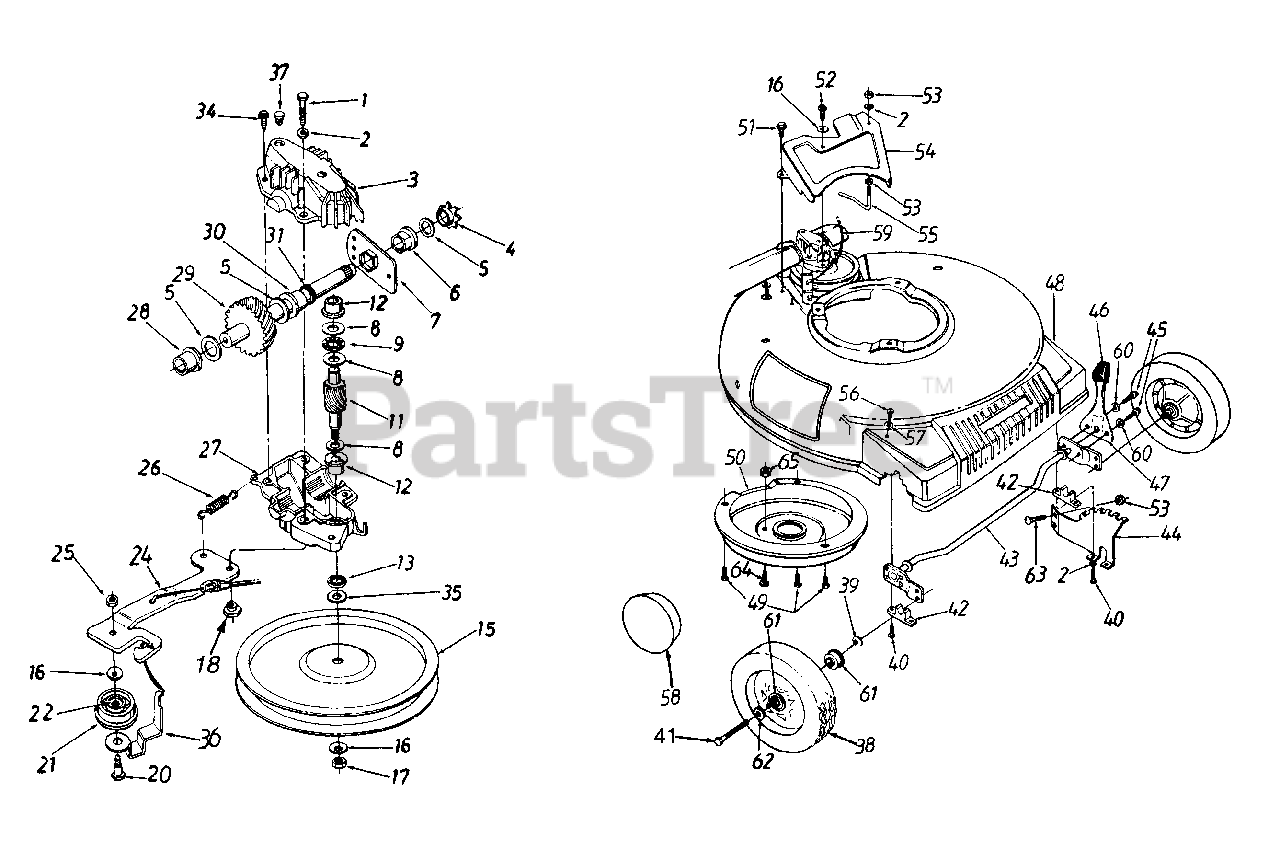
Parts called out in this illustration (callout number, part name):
1	Hex Patch Bolt 1/4-20 x 1.25"
2	L-Wash. 1/4" I.D.
3	Upper Hsg. Half
4	#48 Sprocket 7 T x 1/2 Pitch
5	Fl-Wash. 5/8" I.D. x .030
6	Hex Flange Brg..631" I.D.
8	Thrust Wash. .382" I.D. x .70" O.D.
9	Thrust Bearing .375" I.D. x .812" O.D.
11	11 Tooth Pinion Shaft
12	Flange Bearing
13	Oil Seal
15	Fl-Pulley 5.06" O.D.
16	Bell-Wash..265" I.D. x .75"
17	Hex L-Nut 1/4-28 L.H.Thd.
18	Shld. Spacer .375" Dia. x .170
20	Shld. Bolt.375" Dia. x .40"
21	Fl-Idler Plastic 1.50" Dia.
22	Needle Brg..375" x .31
24	Idler Brk't. Ass'y.
25	Hex Patch L-Nut 1/4-28 Thd.
26	Extension Spring 1.12" Lg.
27	Lower Hsg. Half
28	Flange Bearing .566 Dia.
29	Shaft Ass'y.
30	Flange Bearing .629 Dia.
31	Oil Seal .625 Dia.
34	Hex B-Tap Scr. #10 x .62"
35	Hex Washer .26" x .88"
36	Belt Keeper
37	Plug 1/4 x .437"
38	Wheel Ass'y. Comp. (Gray Rim)
39	Bell-Wash..380" I.D. x .88
40	Hex Wash. Hd. Scr. 1/4 x 1" Lg.
41	Front Axle Bolt
42	Block Bushing
45	Hex TT-Tap Scr. 1/4-20 x .38"
46	Knob
47	Spring Lever
48	Plastic Front End (Black)
49	Hexindwsh 1/4 x .50"
52	Hex Wash. Hd. B-Tap Scr.1/4 x .62"
53	Hex Nut 1/4-20Thd.
56	Torx Truss Hd. Scr. 5/16 x .75"
57	Bell-Wash..345" I.D. x .88"
58	Hub Cap
59	S.P.Cable
60	External L-Wash. 1/4" I.D.
61	Ball Bearing 1/2" I.D.
62	Wave Wash..53" I.D.
63	Carriage Bolt .5" Lg.
64	Mach. Scr. 1/4-20 x 2" Lg.
65	Carr Bolt 1/4-20 x .5" Lg.
